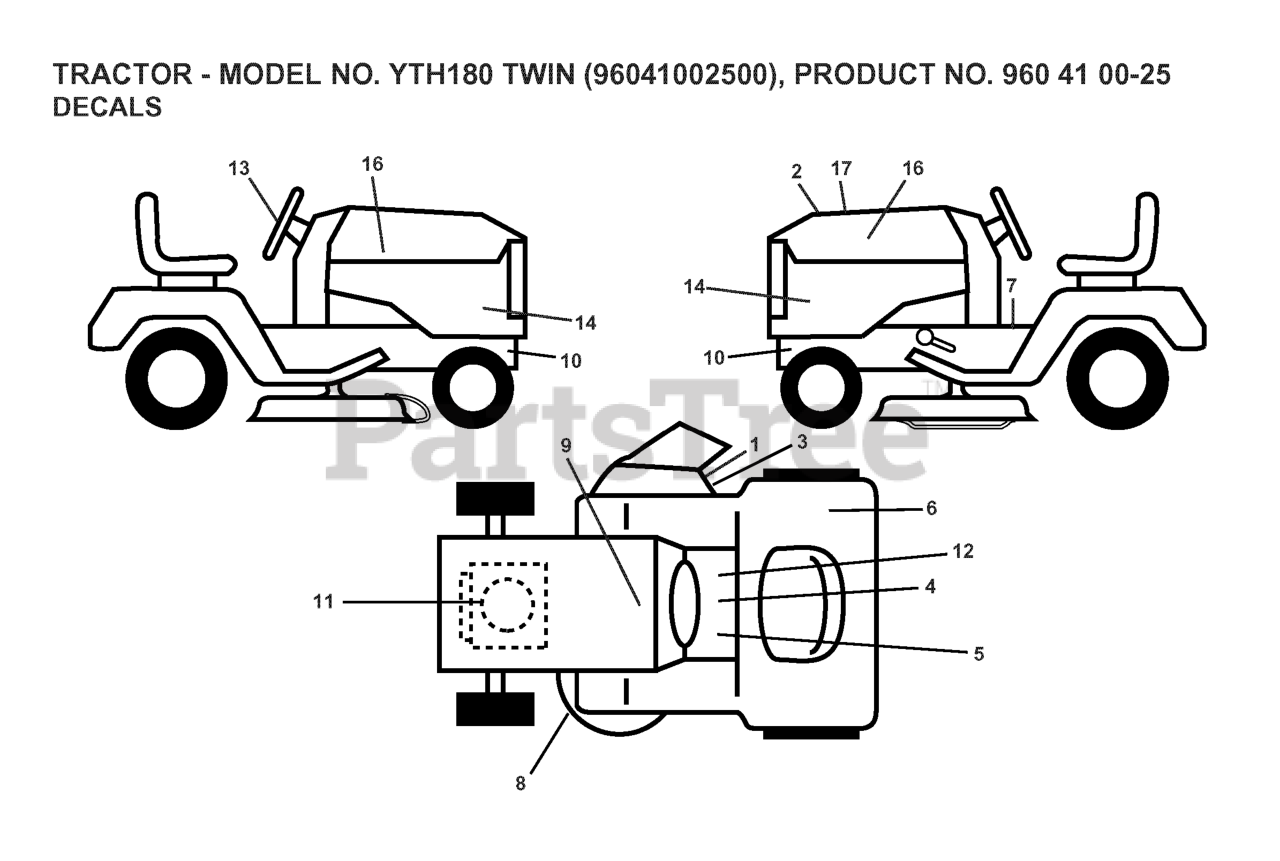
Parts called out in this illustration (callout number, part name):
1	DECAL.INTERNATIONL.CUTFINGER
2	DECAL.HOOD.TOP.INSERT.
3	DECAL, DEFLECT WARNING
4	DECAL PARK BRAKE
5	LABEL
6	Decal, Fender 100 DB/CE
7	DECAL
8	DECAL V BELT SCHEMATIC
9	DECAL BTRY SYMBOLS
11	DECAL
12	DECAL
13	DECAL.WHEEL.STRG.LGN.H
16	DECAL.HOOD.NAMELOGO.HUSQ
